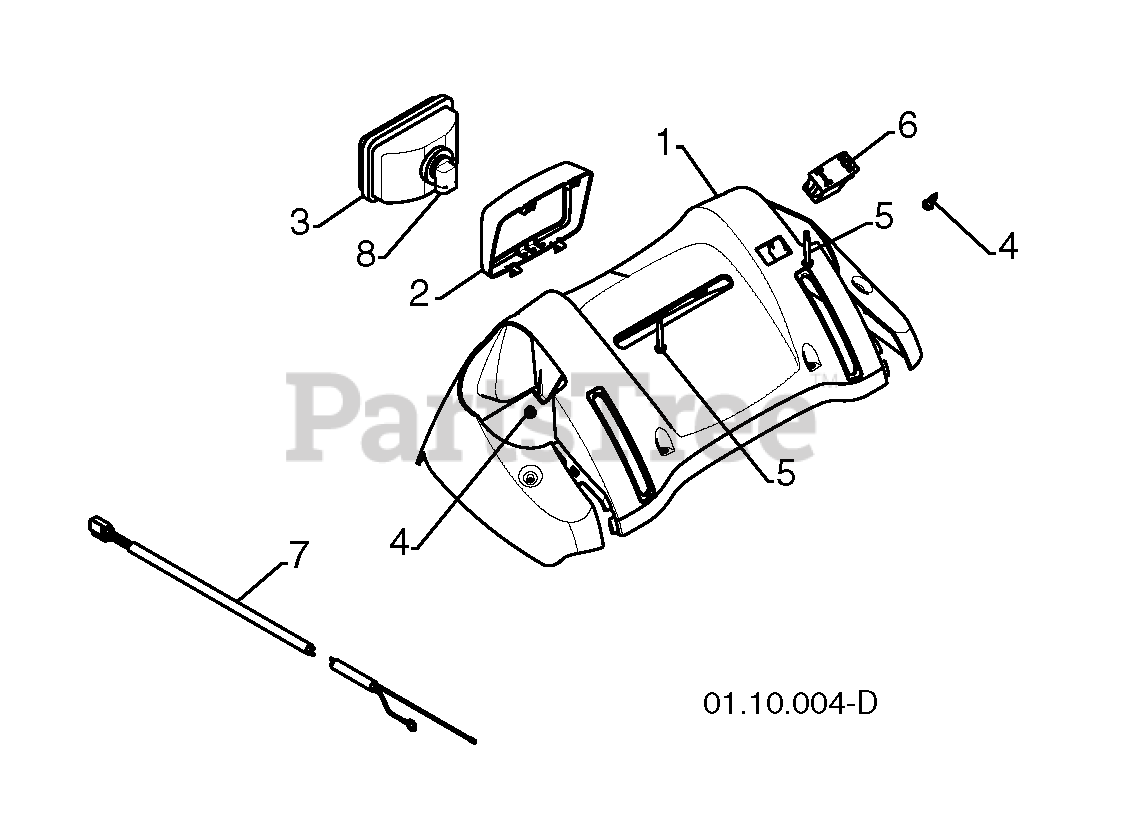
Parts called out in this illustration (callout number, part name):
2	BEZEL.HEADLIGHT.BLACK
3	HEADLIGHT, HALOGEN
4	SCREW, HEX HEAD, TAPPING
5	SCREW, HEX HD TAPPING #10-24 1
6	SWITCH.HEATED.GRIP
7	HARNESS.WIRE.LIGHT/GRIP.SNOW
8	BULB.HEADLIGHT.HALOGEN.
